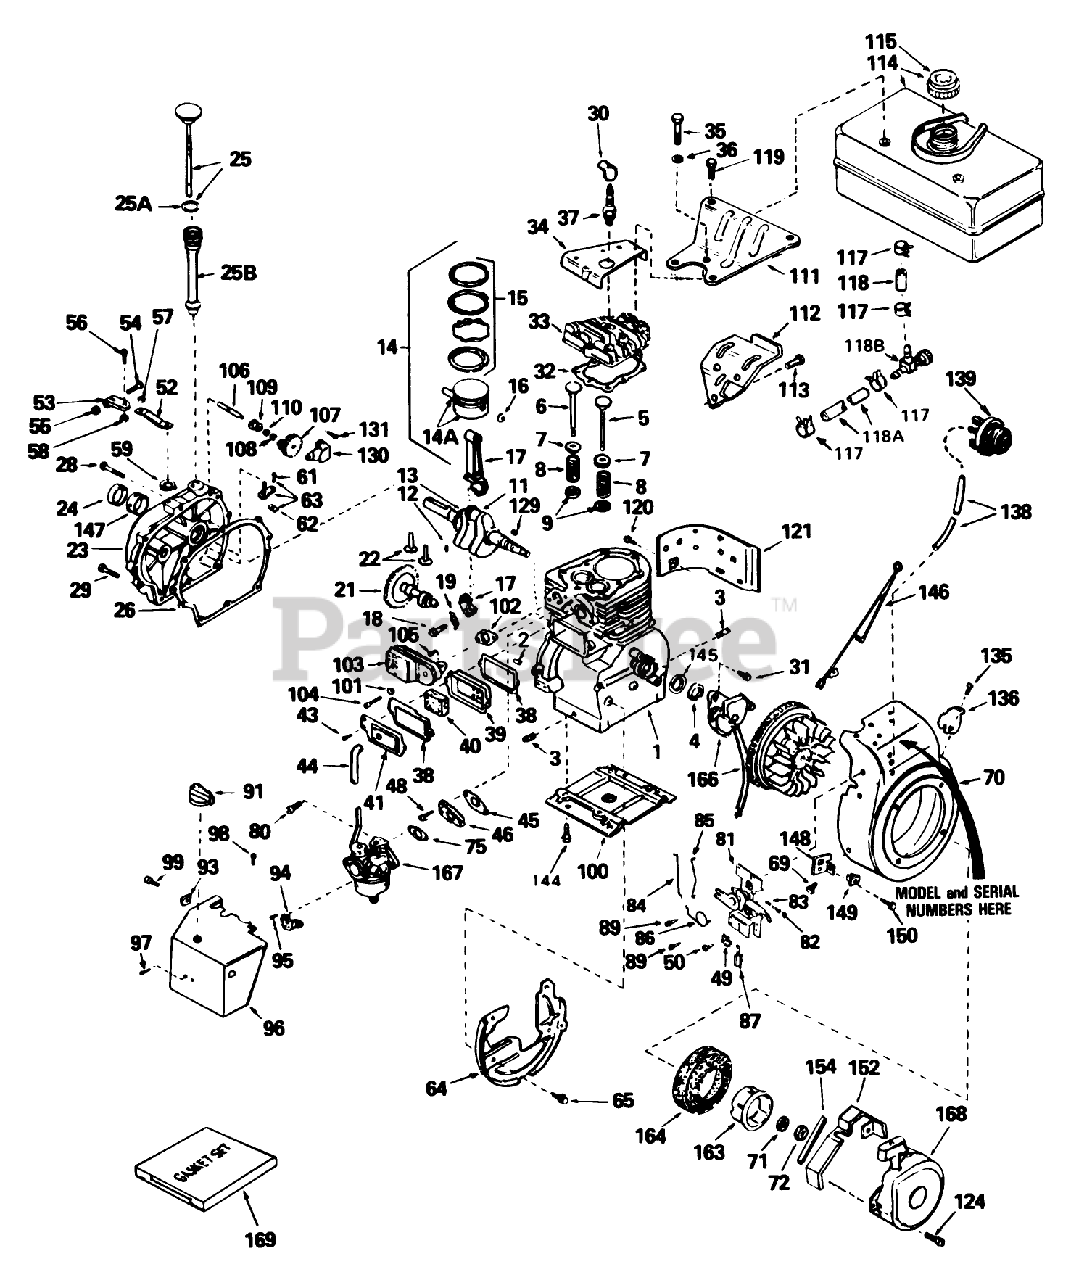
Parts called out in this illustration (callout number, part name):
1	Cylinder Assy. (Incl. Nos. 2, 3 4)
2	Pin-Dowel
3	Plug-Drain, Oil (SQH 1/4-18)
4	Oil Seal
5	Valve, Intake (Standard)(Incl. No. 9)
5	Valve, Intake (1/32" oversize)(Incl. No. 9)
6	Valve, Exhaust (Standard)(Incl. No. 9)
6	Valve, Exhaust (1/32" oversize)(Incl. No. 9)
7	Cap-Spring, Valve
8	Spring-Valve
9	Keeper-Spring, Valve
11	Crankshaft Assy. (Incl. Ref. #12 13)
12	Pin, Groove
13	Gear-Crankshaft
14	Piston, Pin Ring Assy. (Std.) (Incl. Ref. #19A, 20 21)
14	Piston, Pin Ring Assy. (.010 oversize) (Incl. Ref. #19A, 20 21 )
14	Piston, Pin Ring Assy. (.020 oversize) (Incl. Ref. #19A, 20 21)
14A	Piston Pin Assy. (Std.) (Incl. Ref. #20)
14A	Piston Pin Assy. (.010 oversize) (Incl. Ref. #20)
14A	Piston Pin Assy-. (.020 oversize) (Incl. Ref. #20)
15	ORing
15	Ring Set (.010" OS)
15	Ring Set (.020" OS)
17	Rod Assy., Connecting (Incl. Nos. 10 18)
18	Bolt, Connecting Rod
19	Dipper-Oil
21	Camshaft
22	Lifter-Valve
23	Cover, Cylinder (Incl. Nos. 24 106)
24	Oil Seal
25	Dipstick, Oil (Incl. Ref. #88)
25A	O-Ring
25B	Tube Fill
26	Gasket-Cover, Cylinder
28	Screw (1/4-20 x 1-1/4)
29	Screw
30	Cover-Spark Plug
31	Screw
32	Gasket-Cylinder Head
33	CYLINDER HEAD
34	Cover-Head, Cylinder
35	Screw (5/16-18 X 2-1/2)
36	Washer-Flat
37	Plug, Spark (J17LM or equiv.)
37	Plug, Spark (Champion RCJ-8)
38	Gasket-Breather
39	Body-Breather
40	Element-Breather
41	Cover-Valve
43	Screw
44	Tube-Breather
45	Gasket-Intake
46	481-1279 SENATOR RO
48	Screw
49	Conduit
50	Screw (10-32 x 3/8)
52	Lever-Governor
53	Clamp-Lever, Governor
54	Screw
55	Nut-Lock
56	Screw
57	Washer-Lock
58	Nut-Lock
59	Ring-Retaining
61	Screw (6-40x5/16)
62	Yoke-Governor
63	Rod, Governor (Incl. Nos.62 63)
64	Baffle Blower Housing
65	Screw (1/4-20x19/32)
69	Screw, Hex Hd.
70	Housing, Blower (Incl. Ref. #135 136)
71	Washer-Belleville
75	Gasket-Carburetor
80	Screw-Hex Hd.
81	Control Assy., Remote Speed (Incl. Ref. #90 thru 93)
82	Screw
83	Spring-Compression
84	Governor Link
85	Link-Throttle
86	Spring-Throttle
87	Terminal
89	Screw (10-32 x 1/2)
91	Knob-Control
93	Nut-U Type
94	Bracket-Choke
95	Screw (10-32 x 1/2)
96	Cover, Carburetor
97	Screw (8-32 X 5/16)
98	Screw (10-32x1/2)
99	Screw (8-32 x 3/8)
100	Base Engine
101	Washer
102	Gasket Exhaust
103	Muffler
104	Screw (5/16-18 X 2)
105	Screw
106	Shaft-Governor
107	Governor Gear ASM
108	Ring-Retaining
109	Spool-Governor
110	Washer-Flat
111	Bracket-Fuel Tank
112	Bracket-Fuel Tank
113	Screw (1/4-20x19/32)
114	Tank Assy., Fuel (Incl. Ref. #115)
115	Cap, Fuel
117	Clamp-Line, Fuel
118	Line-Fuel
118A	Line-Fuel (8.62)
118B	Valve-Shut Off
119	Screw (1/4-15x7/8)
120	Screw
121	Emnsion, Blower Housing
124	Screw
129	Key-Flywheel
130	Bracket, Governor
131	Screw (10-24x1/2)
135	Screw (8-32 x 3/8)
136	Screw
138	Line, Primer
139	Primer Assy.
144	Screw
145	Gasket Stator
146	Wire, Ground
147	Bushing-Crankshaft
148	Bracket
149	Grommet
150	Screw
152	Guard-Starter
154	Seal, Snowguard
163	Cup-Starter
164	Screen, Air
166	Magneto(The complete magneto is not available as an assembly. The magneto number is shown for reference purposes only. Order component parts individually,as shown in parts list.)
167	Carburetor (Incl. No. 75)
168	Starter Assy., Rewind
169	Gasket Set
